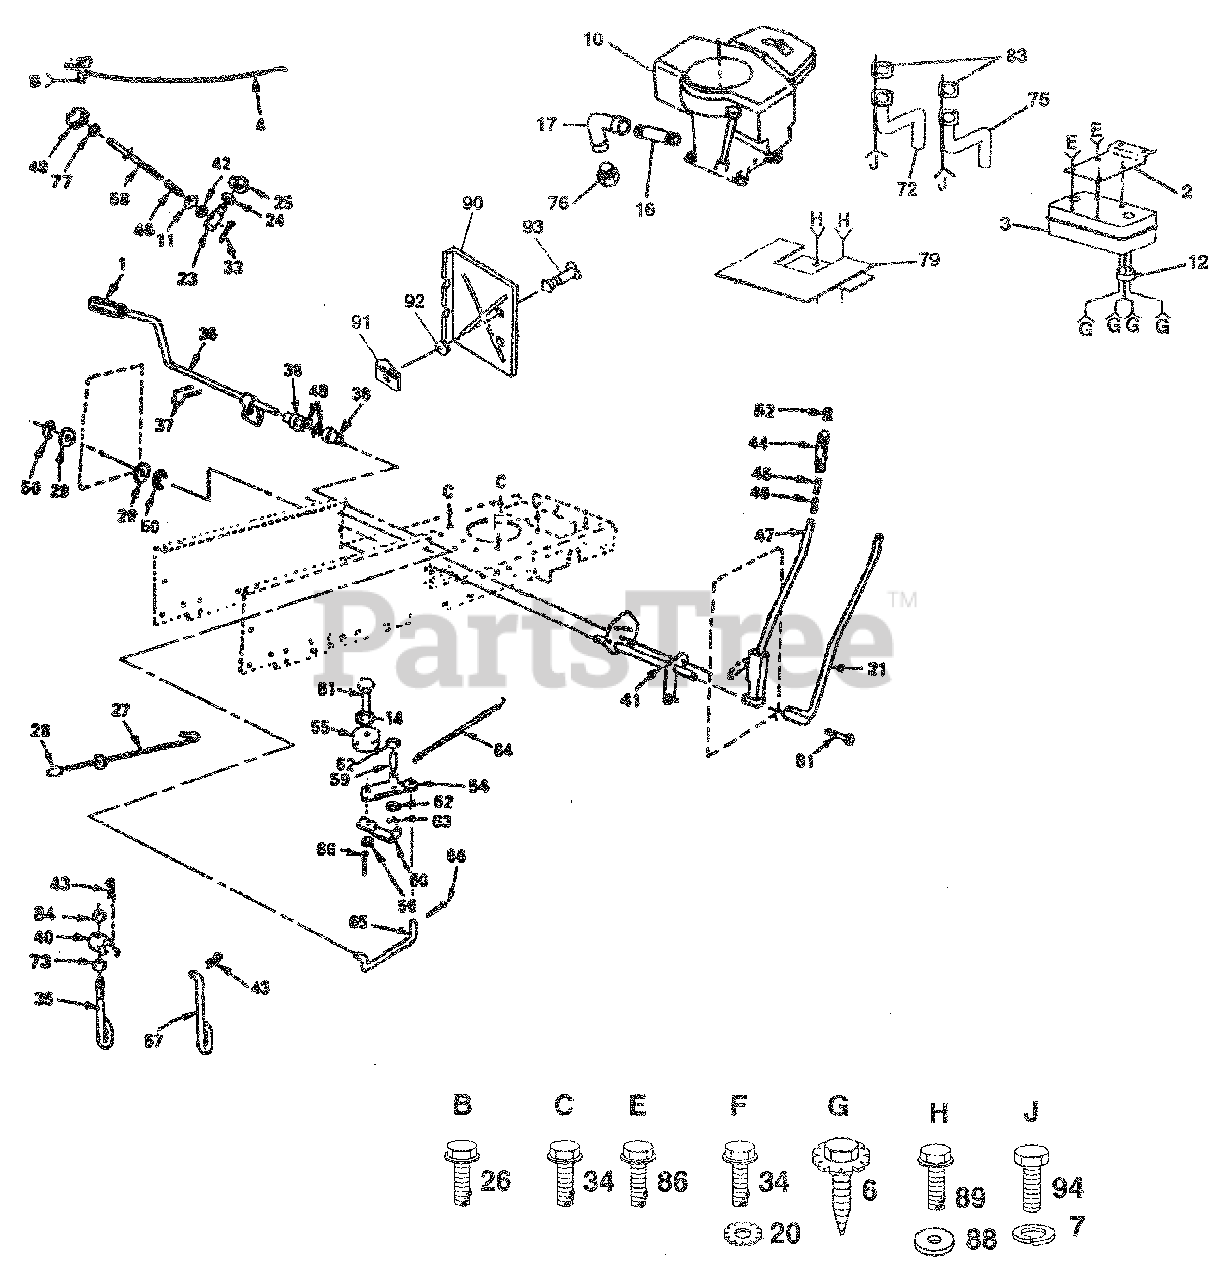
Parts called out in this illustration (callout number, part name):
1	Cover, Pedal
2	Bracket, Muffler, Mounting
4	Control, Throttle
6	Screw, Spiderloc Hex Hd #8 x 1/2 AB
7	Washer, Lock 1/4
11	Washer 13/32 x 5/8 x 16 Gauge
12	Deflector, Muffler
14	Washer 13/32 x 13/16 x 16 Gauge
16	Pipe Nipple, Standard
17	90° Elbow, 3/8 NPT
20	Washer, Lock, External Tooth 3/4
21	Rod Assembly, Lever
23	Trunnion, Depth Stop
24	Washer 15/32 x 3/4 x 16 Gauge
25	Ring, Klip
26	Screw, Hex Washer Head, Thread Cutting 1/4-20x5/8
27	Rod, Brake, Park
28	Cap, Parking Brake
29	Washer 29/32 x 1-1/4 x 16 Gauge
33	Pin, Cotter 3/32 x 1/2
34	Screw, Hex Washer Head, Thd. Roll. 3/8-16 x 1-1/2 Type TT
35	Lift, Link, Adjustable
36	Shaft, Pedal, Foot
37	Roll Pin 3/16 x 1
38	Bearing, Nylon
40	Trunnion, Lift
41	Shaft Assembly, Lift
42	Nut, Hex, Special
43	Retainer, Spring
44	Grip, Handle
45	Plunger, Lever, Lift
47	Lever Assembly, Hand Kit
48	Washer 21/32 x 1 x 16 Gauge
49	Knob, Infinite 3/8-18
52	Button, Plunger
54	Arm Assembly, Idler
55	Pulley, idler
56	Nut, Crownlock 3/8-16
57	Link, Lift
58	Rod, Adjust, Lift
60	Retainer, Beit
61	Bolt, Hex 3/8-16 x 1-1/2
62	Washer, Hardened
63	Ring, Klip
64	Spring, Return, Clutch
72	Tube, Manifold, L H .
73	Nut, Hex, Jam 7/16-20
75	Tube, Manifold, R.H.
76	Oil Drain Plug
77	Nut, Hex, Jam 3/8-16
79	Shield, Heat
81	Bolt, Hex 3/8-16 x 1-1/2
83	Gasket, Muffler
84	Nut, Crownlock 7/16-20
85	Link, Clutch
86	Pin, Cotter 1/8 x 3/4
86	Screw, Hex Wash Thdcut 1/40-20 UNC
88	Washer 13/32 x 1 x 14 Ga.
89	Screw, Thdrol 5/16-18 x 3/4
90	Shield, Heat 1/4 Turn
91	Receptacle 1/4 Turn
92	Retainer 1/4 Turn
93	Stud 1/4 Turn
94	Bolt, Hex 1/4-20 x 3/4
